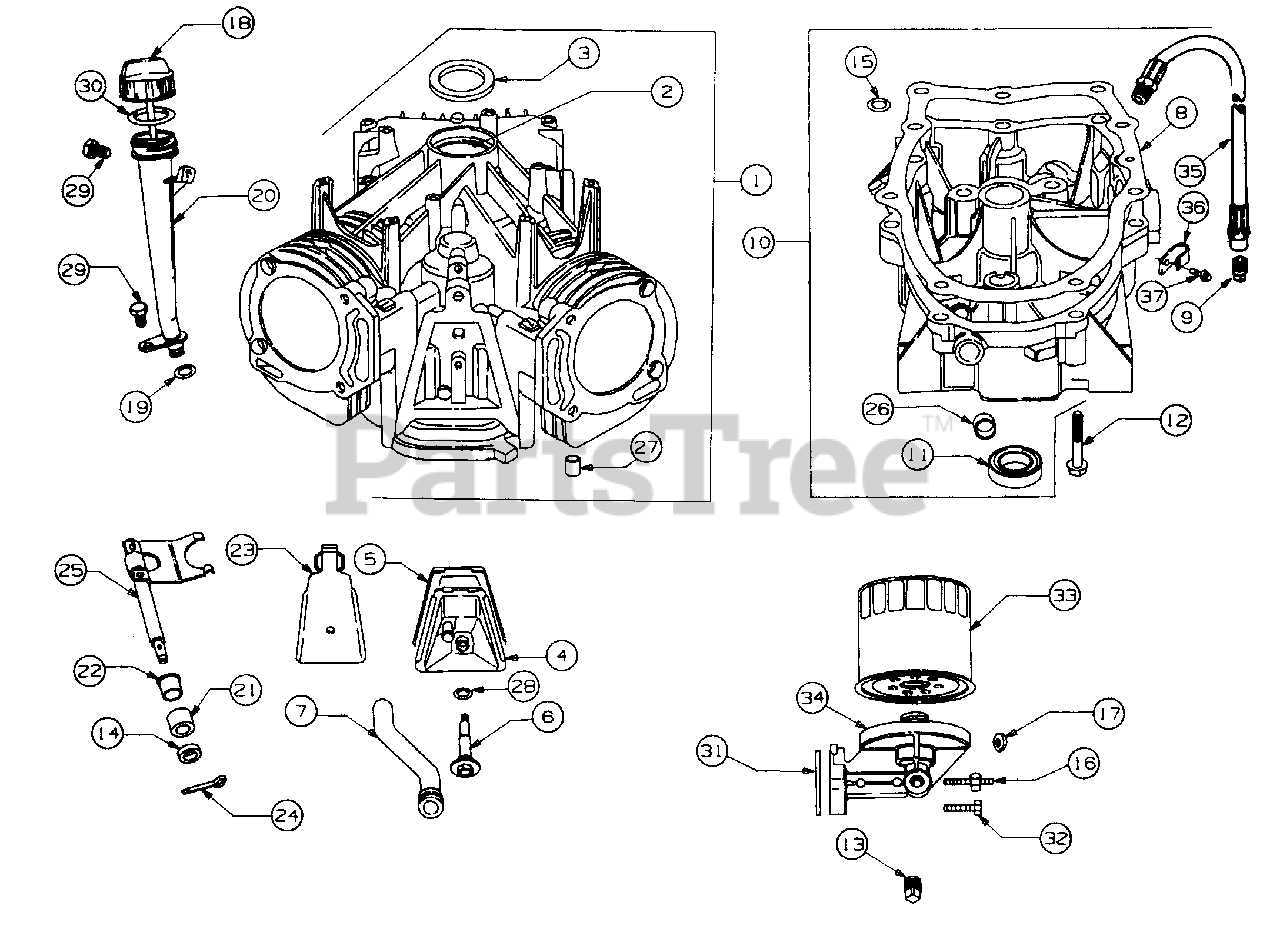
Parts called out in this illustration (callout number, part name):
1	Cylinder Assy
2	Bearing, Cylinder
3	Seal, Oil
4	Breather Assy
5	Gasket, Breather
6	Screw, Breather
7	Tube, Breather
8	Gasket, Crankcase Cover
9	Plug, Oil Drain
10	Cover Assy, Crankcase
11	Seal, Oil
12	Screw, Crankcase Cover
13	Plug, Pipe
14	Seal, Governor Shaft
15	O-Ring (Crankcase Cover)
16	Stud, Oil Filter Adapter
17	Washer, Lock
18	Dipstick
19	Seal, Filler Tube
20	Tube, Off Filler
21	Bushing, Governor Shaft
22	Bushing, Governor Shaft
23	Baffle, Breather
24	Pin, Cotter
25	Fork, Governor
26	Washer, Governor Shaft
27	Dowel, Crankcase
28	Seal, Breather Screw
29	Screw, Mounting
30	O-Ring
31	Gasket, Oil Filter Adapter
32	Screw, Sem
33	Filter, Oil
34	Adapter, Oil Filter
35	Hose, Oil Drain
36	Clip, Drain Hose
37	Screw, Hex Wash Hd Tapp 5/16-18 X .50 Lg
